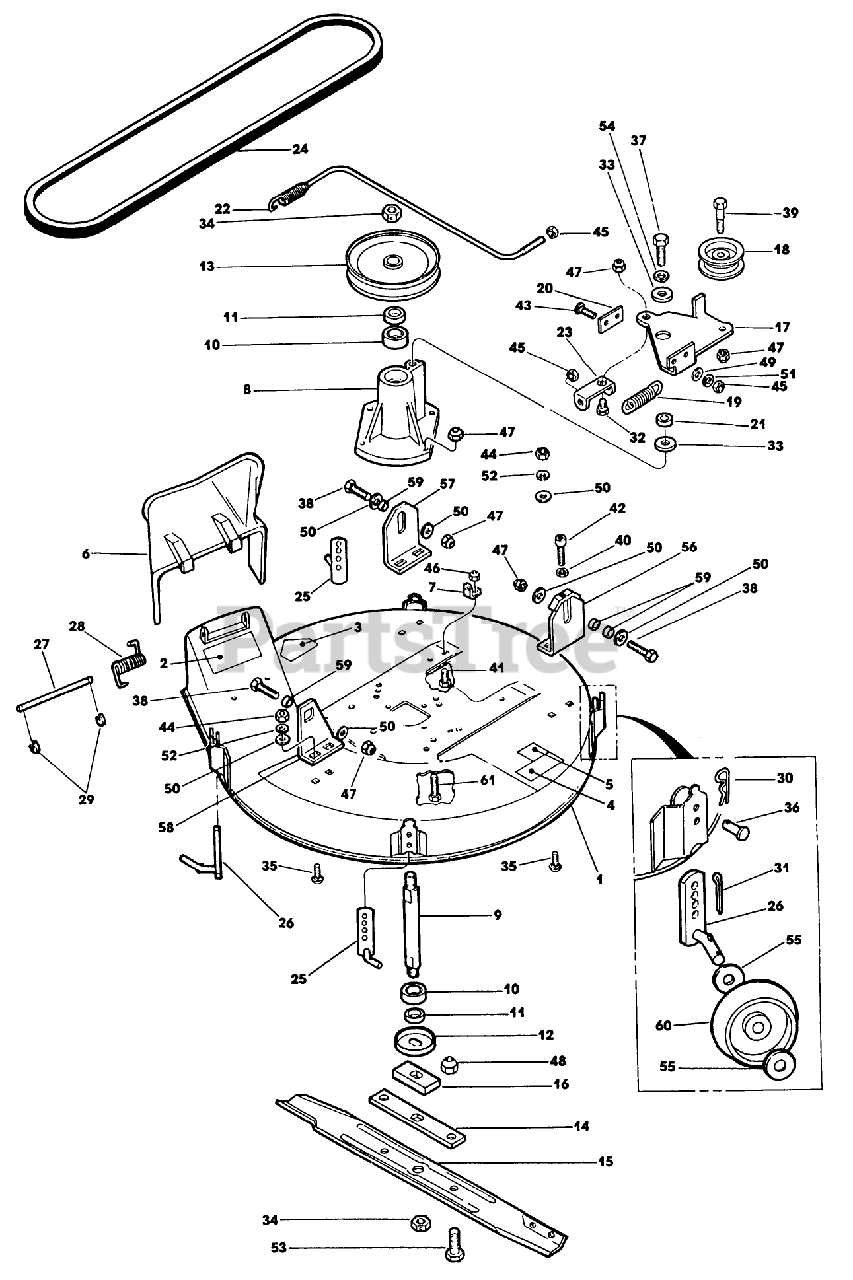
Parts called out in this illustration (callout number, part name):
4	DECAL
6	EXTENSION -CHUTE
8	HOUSING,MOWER SPINDLE
9	SHAFT-SPINDLE
11	SPACER
19	SPRING
24	V-BELT
27	SHAFT - CHUTE
29	E-RING
30	PIN - SPRING CLIP
33	WASHER
34	LOCKNUT-SPECIAL
36	PIN - CLEVIS
41	SCREW-HH
44	NUT
45	NUT
46	NUT-LOCK, CONE
47	NUT-LOCKING
48	NUT-HEX CONE LOK
50	WASHER
52	WASHER
53	SCREW
56	LH REAR HNGR BRKT WA*G
58	BRACKET*G
59	BUSHING
60	WHEEL-GAGE
